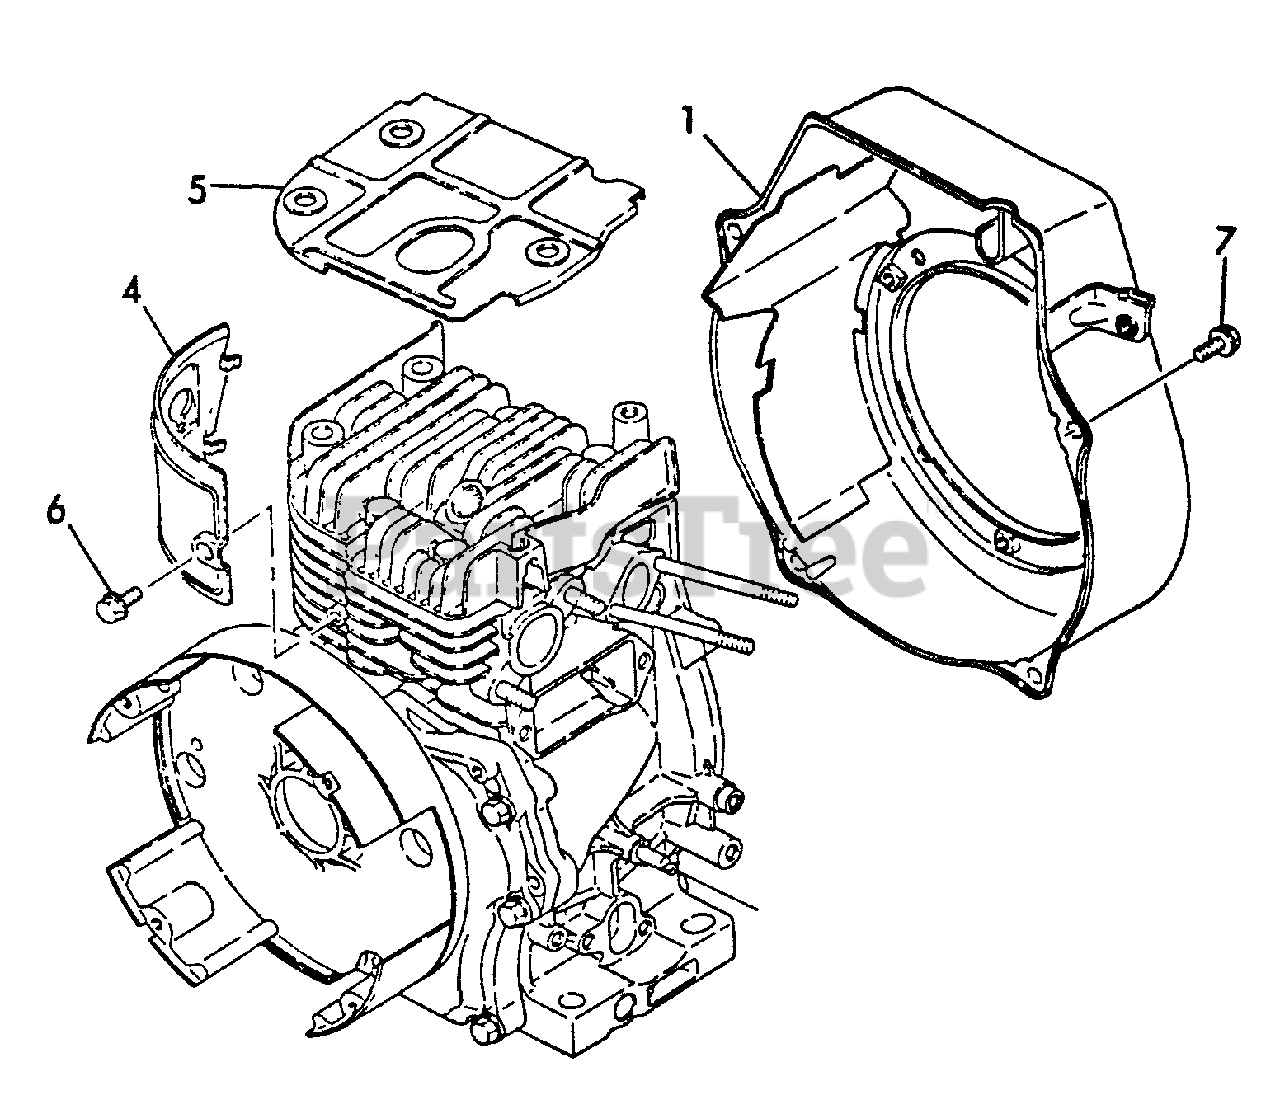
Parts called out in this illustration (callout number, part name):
1	CASE, FAN
4	PLATE
5	COVER, HEAD
6	BOLT - 6×8 -- PLATED
7	BOLT - 6×8 -- PLATED
